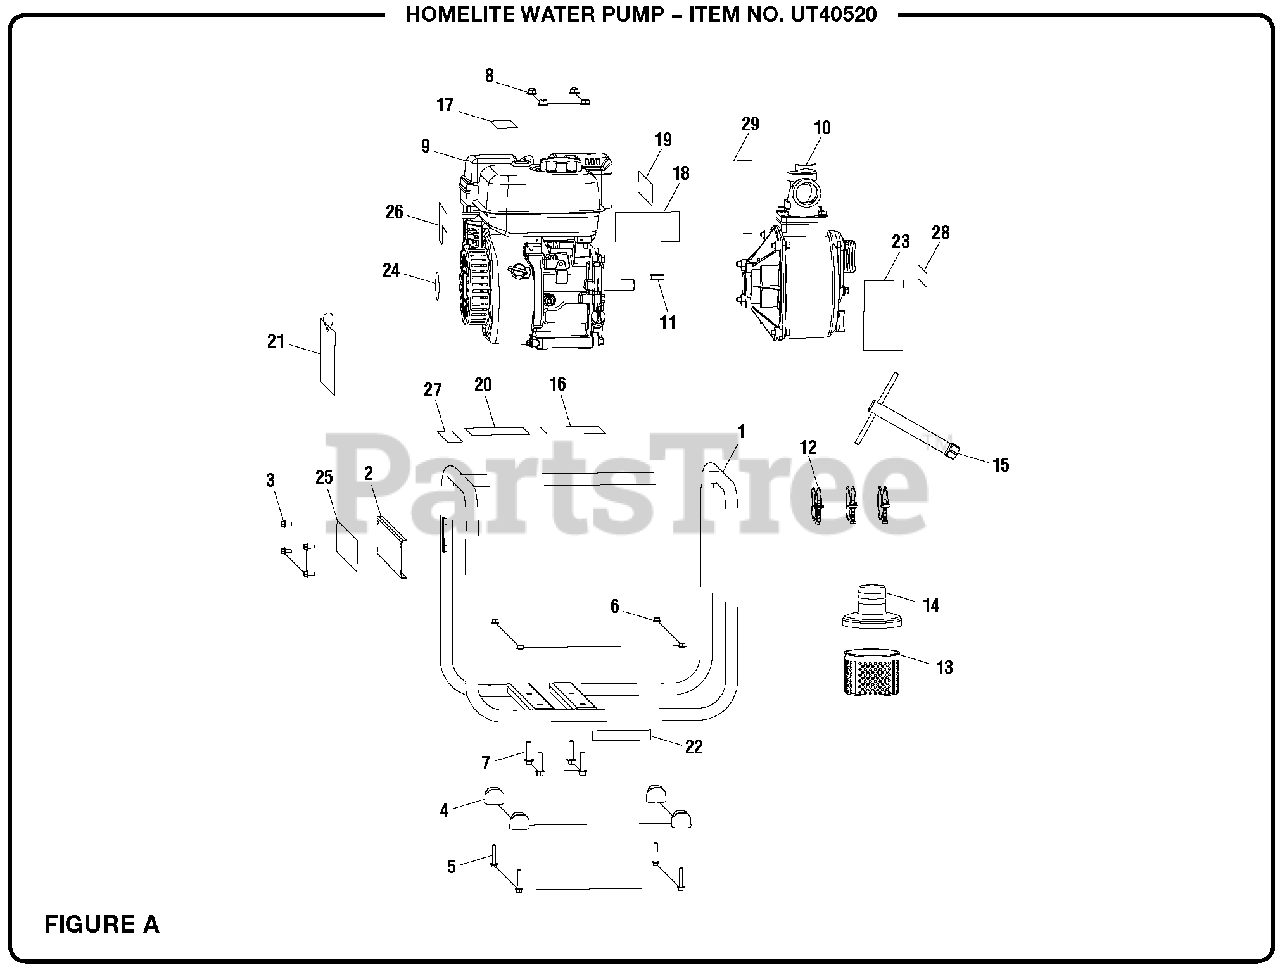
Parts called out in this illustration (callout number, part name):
1	Frame Assembly
2	Front Panel
3	Bolt (M6 x 12 mm)
4	Rubber Foot
5	Bolt (M6 x 35 mm, Flange Hd)
6	Lock Nut (M6, Flange Hd)
7	Bolt (M8 x 35 mm, Flange Hd)
8	Lock Nut (M8)
10	Pump Assembly
11	Output Shaft Key
12	Hose Clamp
14	Filter Cap
15	Spark Plug Wrench
16	Hot Surface Label
17	CPSC Label
18	Danger Label
19	E85 Label
20	Combustion Label
21	Danger Hangtag
22	Lubricant Label
23	Quick Start Label
24	Recoil Housing Label
25	Performance Label
26	Choke Label
27	EMC Label
28	Do Not Operate Label
29	Fire Danger Label
